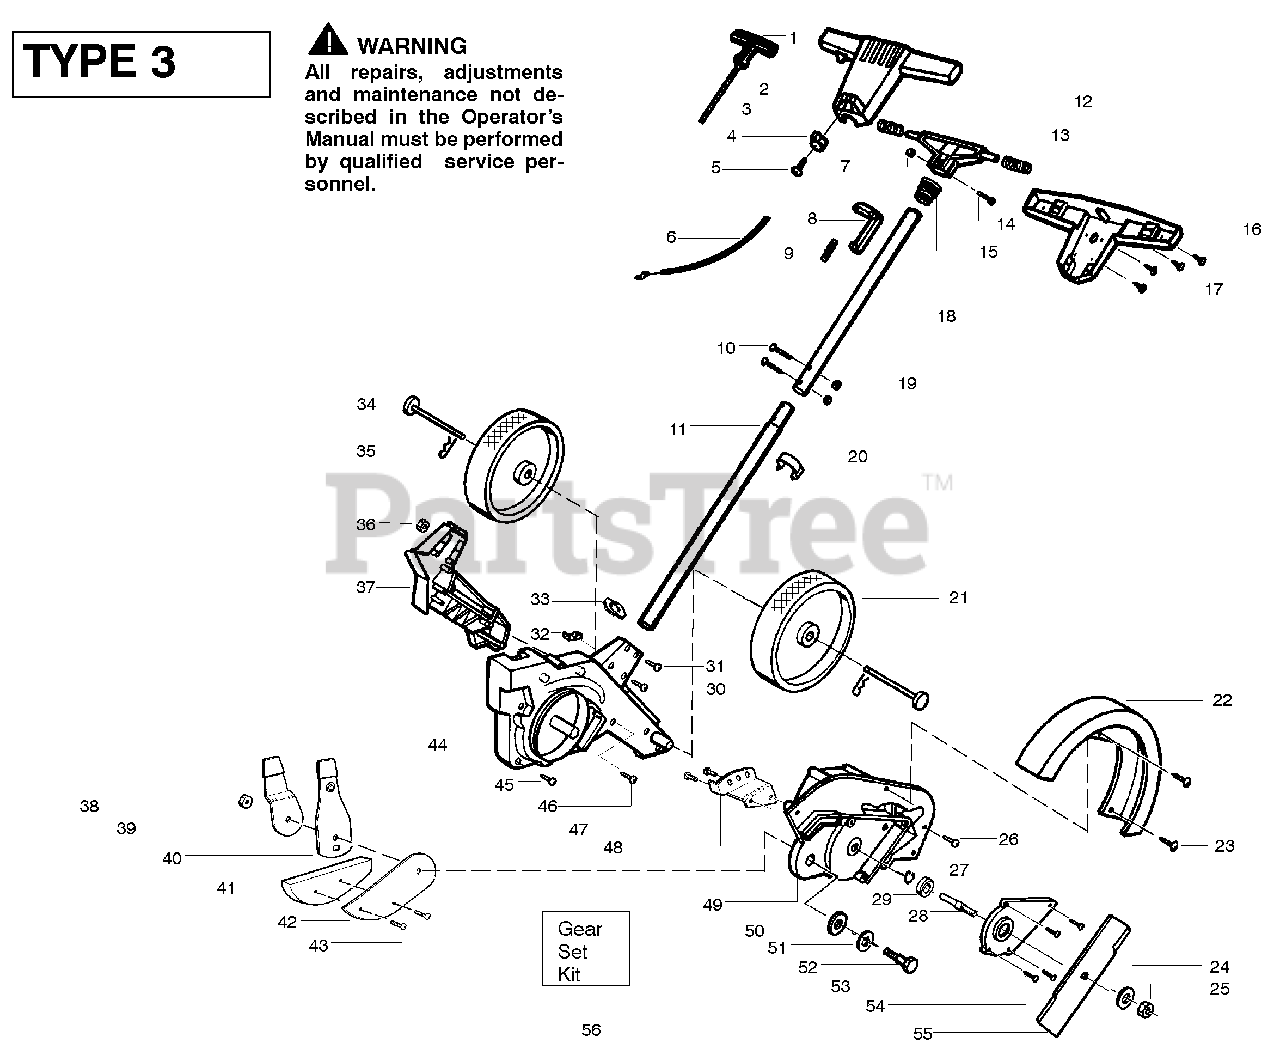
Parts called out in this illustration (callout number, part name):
1	Handle-Starter
2	Handle-Upper
3	Kit-Rope
4	Eyelet-Handle
6	Assy-Throttle Cable
8	Trigger-Throttle
9	Spring-Throttle
10	Bolt-Shoulder Tube
11	Tube-Lower Handle
12	Coupling-Handle
13	Spring-Isolator
15	Spring-Handle
16	Handle-Lower
18	Tube-Upper Handle
20	Clamp-Cable
21	Wheel-Rear
22	Shield-Front Blade
24	Washer-Belleville
27	Retainer Ring-Flat
28	Shaft-Output
29	Washer-Thrust
32	Nut-Speed
33	Gasket-Tube
34	Pin-Axle
35	Bridge-Pin
37	Cover-Axle
38	Nut-Swing Arm
39	Lever-Limiter
40	Assy-Lever Adjustment
41	Foot-Skid
42	Arm-Swing
44	Housing-Fan
48	Plate-Back
49	Assy-Gear Box
50	Washer-Bolt Adjust
51	Washer-Wave
52	Bolt-Shoulder
53	Assy-Bearing Holder
56	Kit-Gear Set
